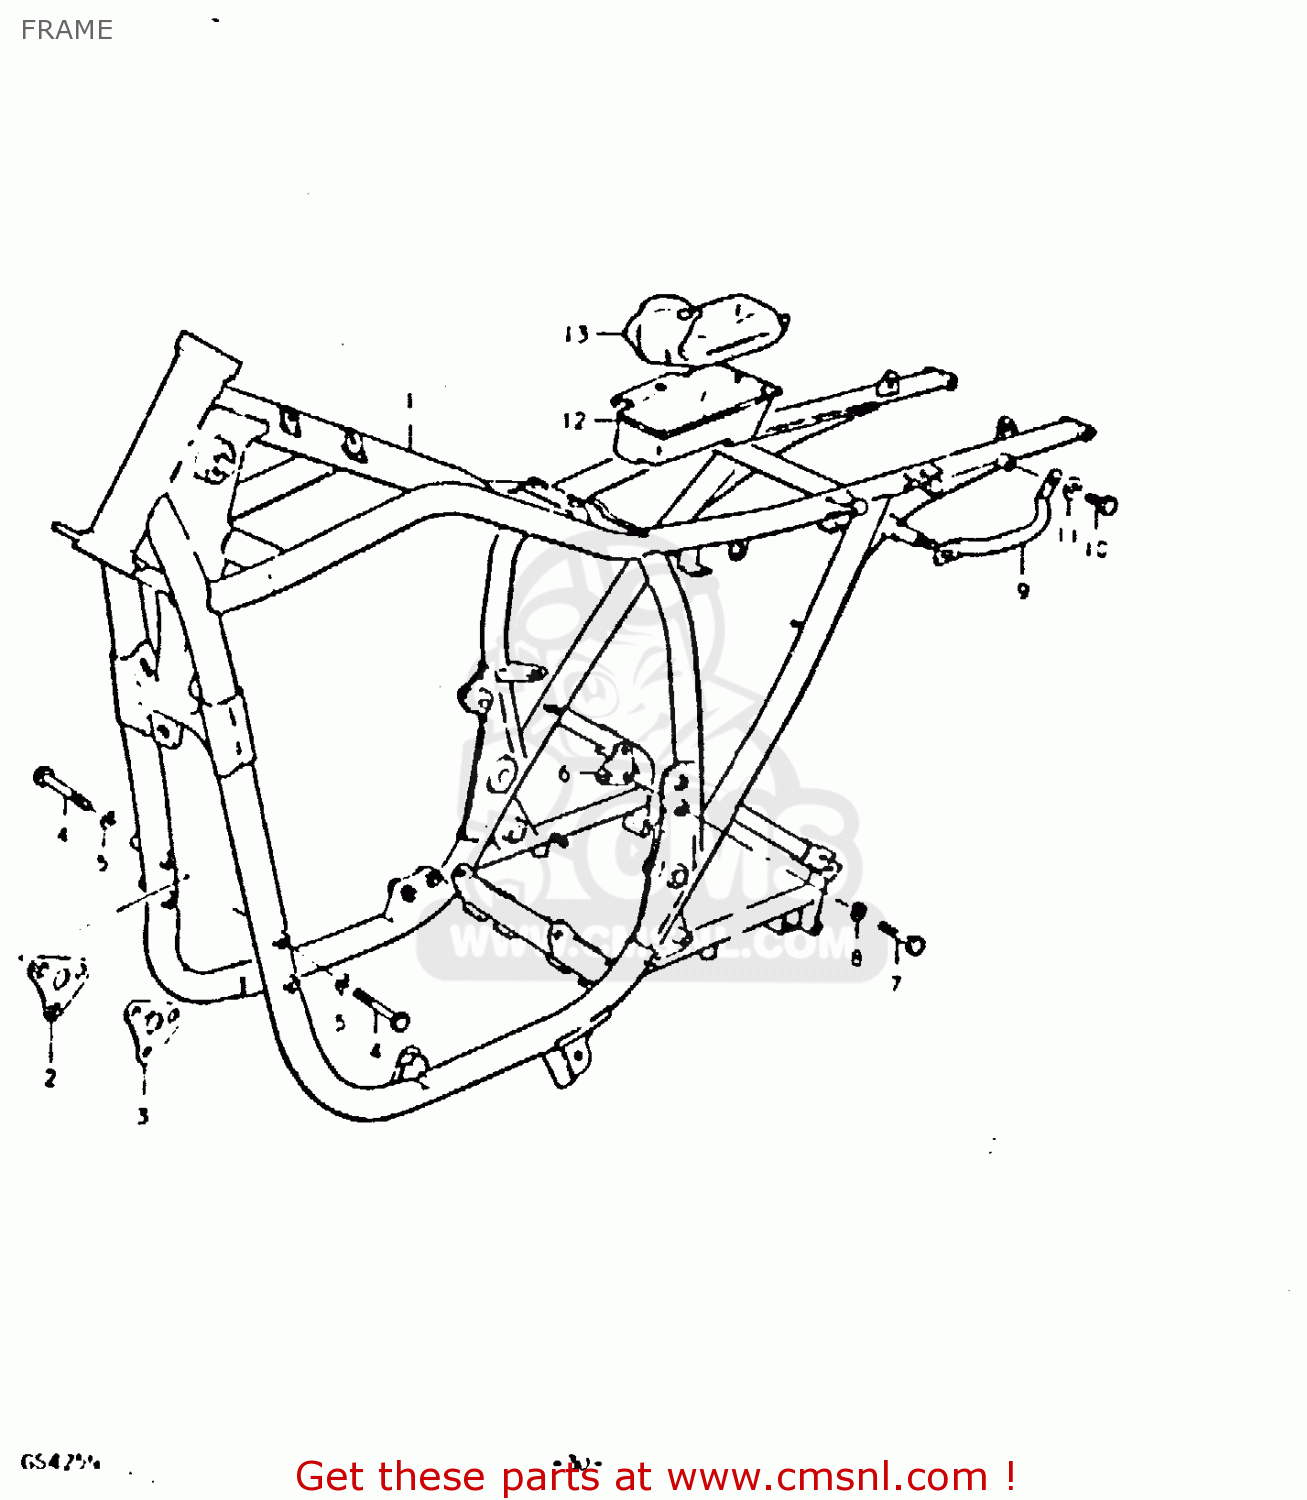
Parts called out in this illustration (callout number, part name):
1	FRAME
2	PLATE,ENGINE MOUNTING
3	PLATE,ENGINE MOUNTING
4	BOLT
5	LOCK WASHER
6	PLATE,ENGINE MOUNTING
7	BOLT 8X40
8	LOCK WASHER
9	GRIP,FRAME HANDLE
10	BOLT
11	WASHER
12	HOLDER,TOOL
13	TOOL SET
